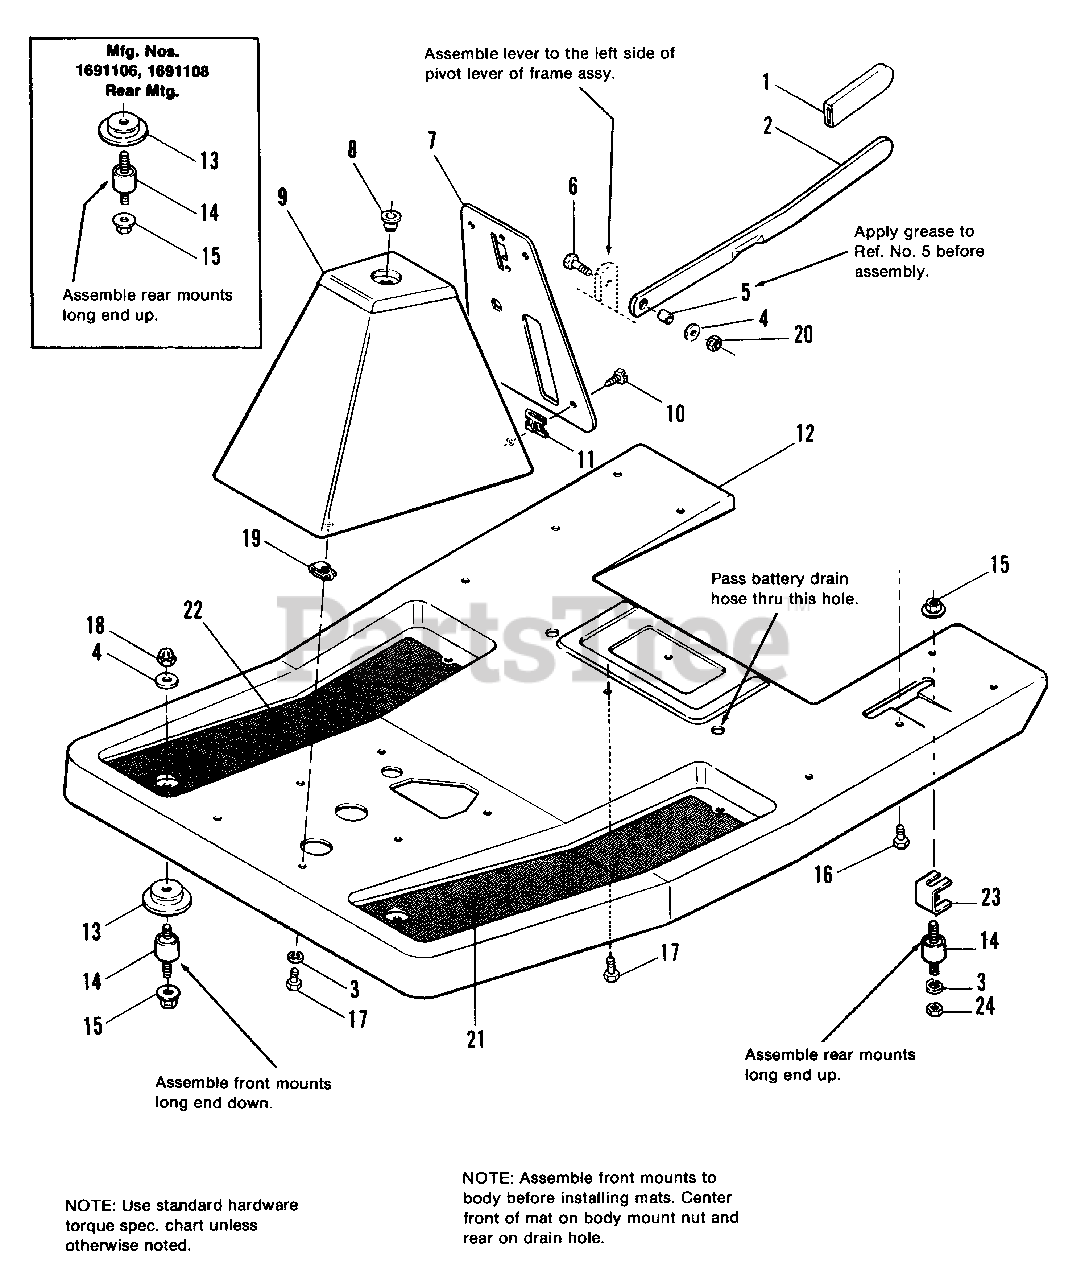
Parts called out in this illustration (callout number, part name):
1	GRIP, Lever
2	LEVER, Lift
3	LOCKWASHER, 5/16
4	WASHER, Plain, 5/16
6	CAPSCREW, Hex, 5/16-18 x 1
7	PANEL, Steering Column
8	BUSHING, Nylon
9	STEERING COLUMN ASSY.
10	SCREW, Hex, Thd. Forming, #10 x 1/2
11	U-NUT, #10 x 1/2
12	BODY, Front
13	RESTRAINER (Qty. 4 on Mfg. No.1691106 & 1691108)
14	CONNECTOR, Cushion
15	LOCKNUT, Flange, Whiz, 5/16-18
16	CAPSCREW, 5/16-18 x 5/8
17	CAPSCREW, Hex Hd., 5/16-18 x 3/4
18	NUT, Acorn, 5/16-18
19	NUT, Speed, 5/16-18
20	LOCKNUT, Hex, 5/16-18
21	MAT, Foot, L.H.
22	MAT, Foot, R.H.
23	CLIP, Up-Stop (Not used on Mfg. No. 1691106, 1691108)
24	NUT, Hex, 5/16-18 (Not used on Mfg. No. 1691106, 1691108)
